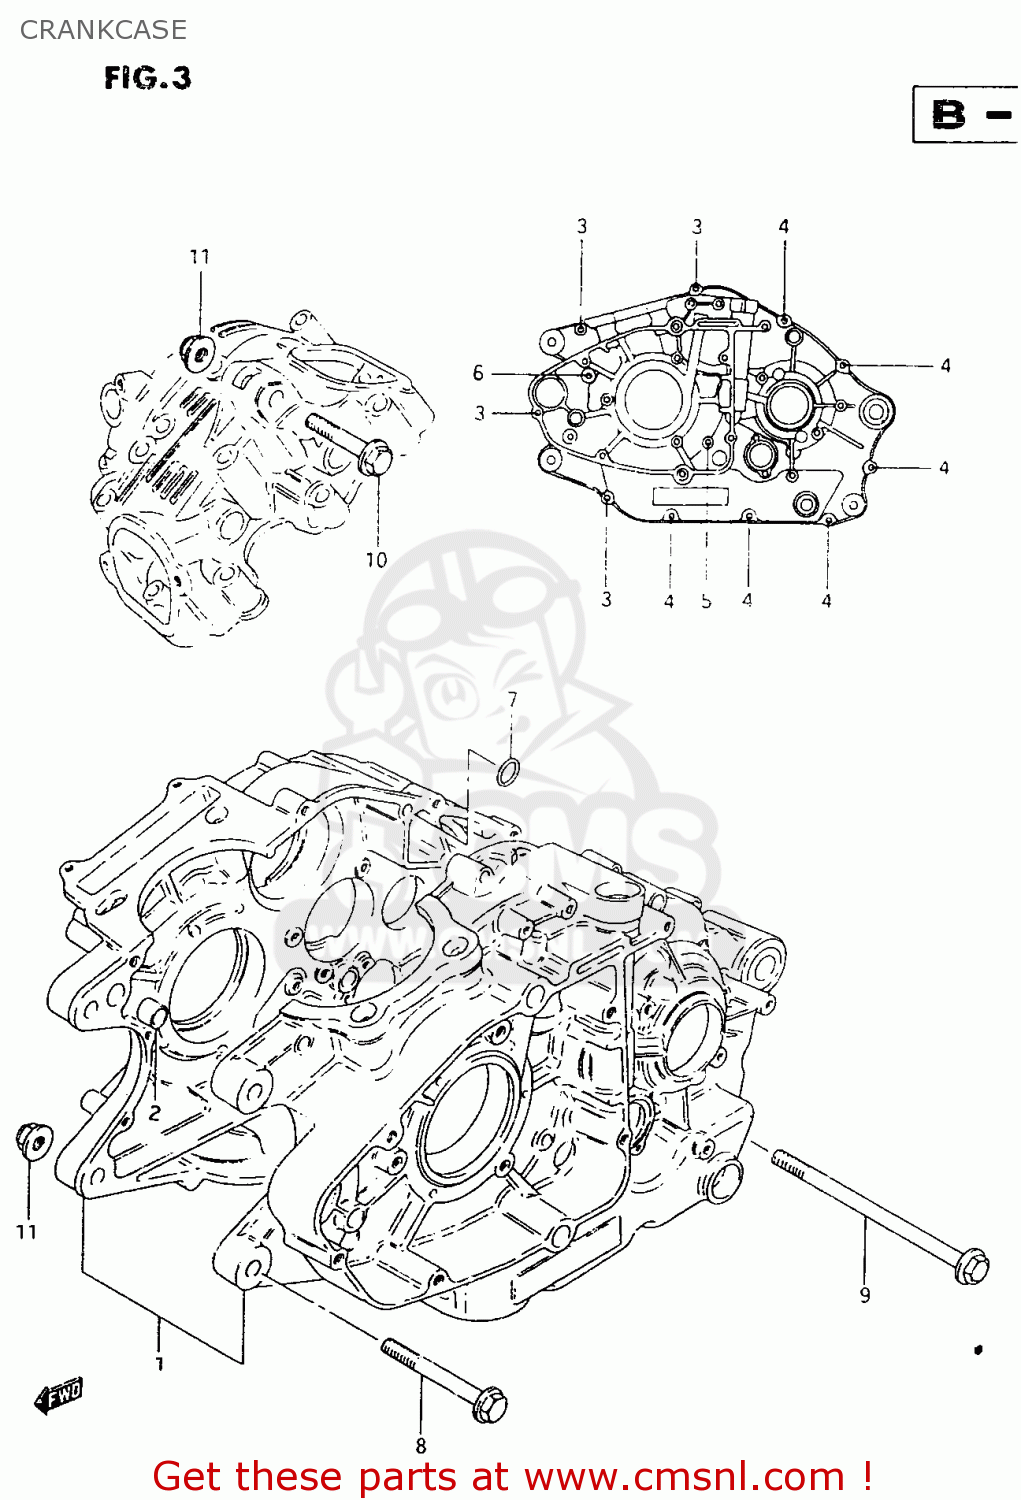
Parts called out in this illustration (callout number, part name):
1	CRANKCASE SET
2	PIN
3	BOLT
4	BOLT
5	BOLT
6	BOLT
7	O RING(D:1.9,ID:9.8)
8	BOLT(8X67)
9	BOLT(8X100)
10	BOLT(8X50)
11	NUT
